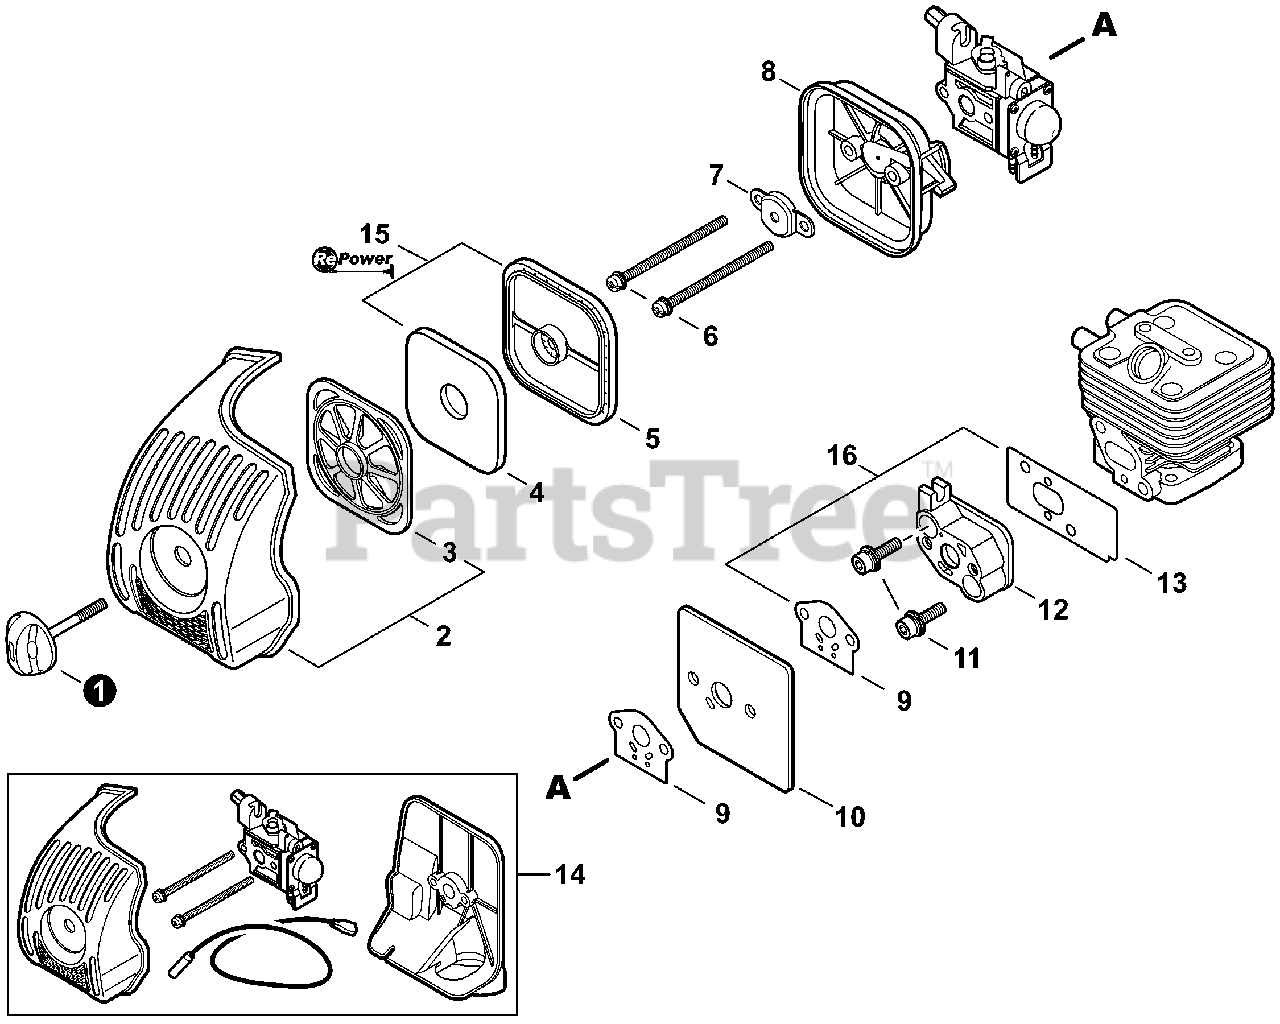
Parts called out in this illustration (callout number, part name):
1	THUMBSCREW
2	COVER KIT, AIR FILTER
3	RETAINER, PRE-FILTER
4	PRE-FILTER, FOAM
5	FILTER, AIR - DOUBLE LAYER
6	SCREW 5×65
7	PLATE, PREVENT
8	CASE, AIR FILTER
9	GASKET, INTAKE
10	PLATE, INSULATOR
11	BOLT 5×25
12	INSULATOR, INTAKE
13	HEAT SHIELD, INTAKE
14	HOT START KIT 266
15	TUNE-UP KIT - REPOWER
16	GASKET KIT
